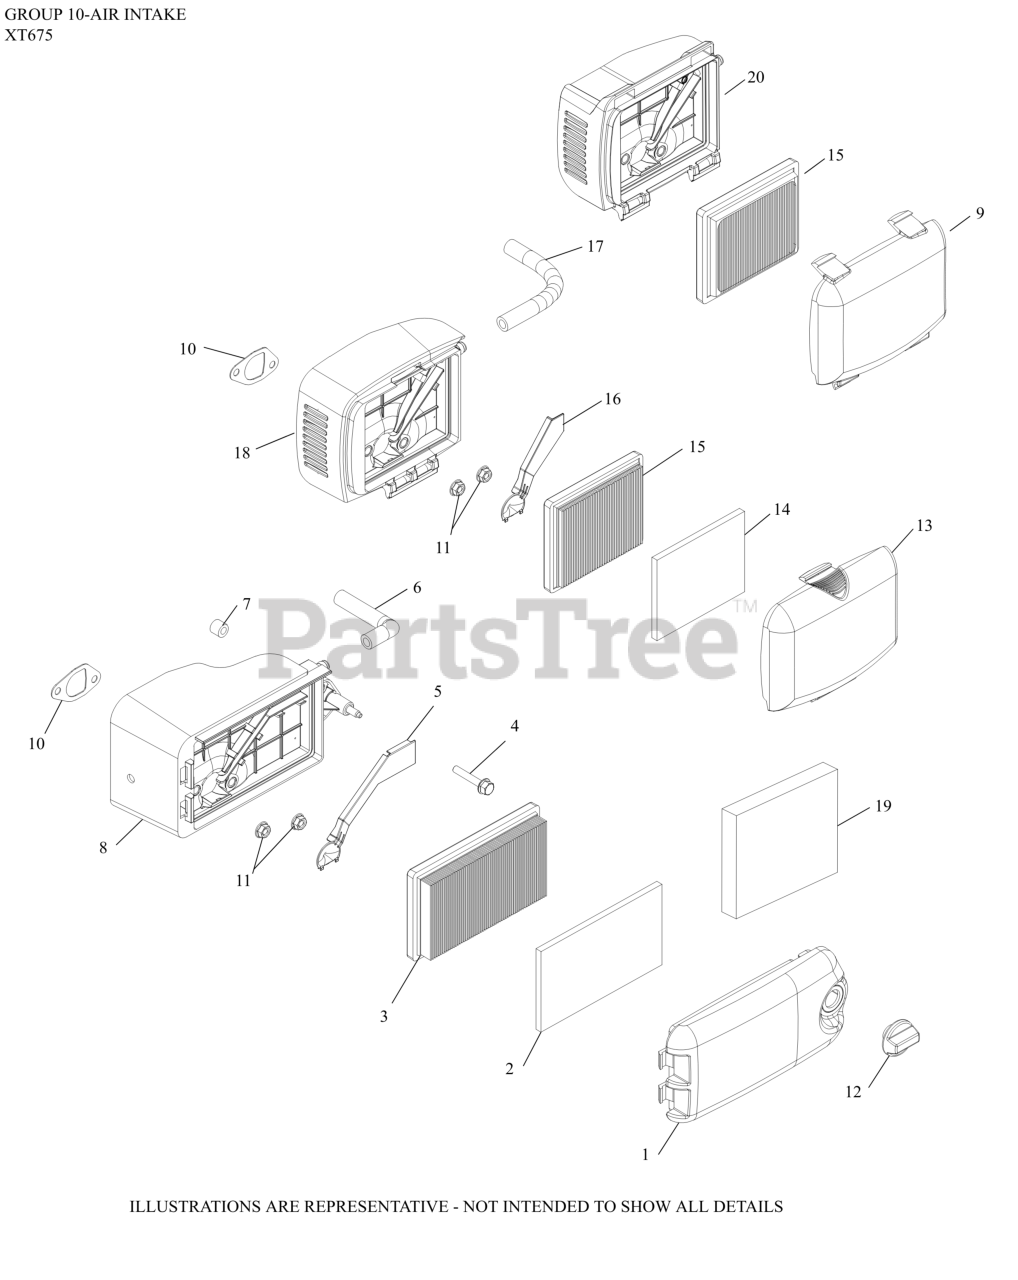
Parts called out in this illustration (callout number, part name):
10	KIT, INTAKE GASKET
13	COVER AIR CLEANER-USE 14 743 03-S
17	HOSE, BREATHER
18	KIT, AIR CLEANER BASE-USE 14 743 03-S
